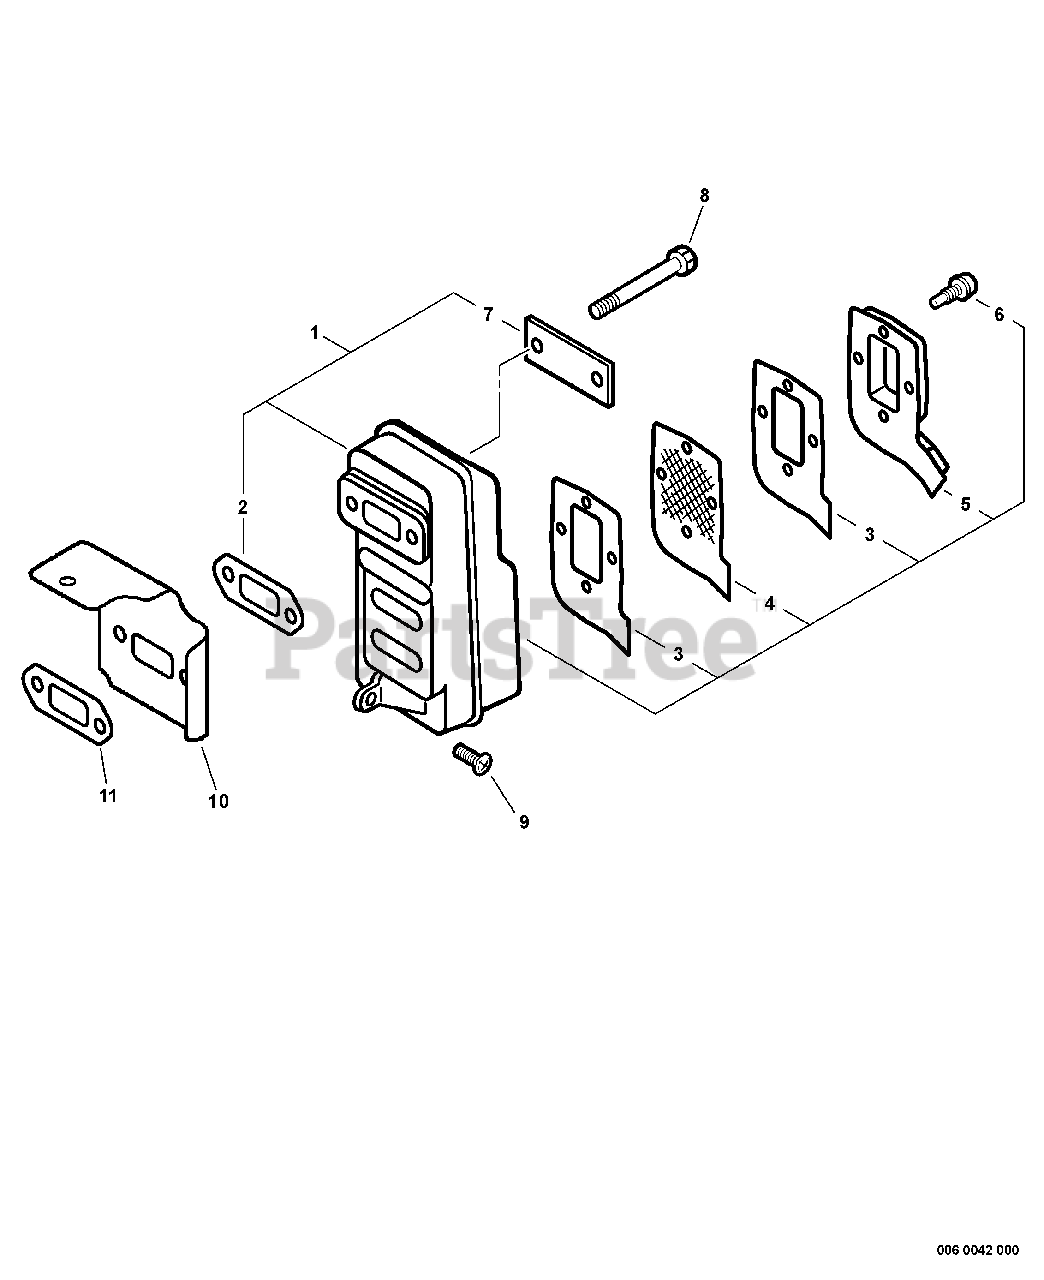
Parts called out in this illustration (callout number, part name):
1	MUFFLER ASSY
2	GASKET, EXHAUST
3	GASKET, EXHAUST
4	SCREEN, SPARK ARRESTER
5	GUIDE, EXHAUST
6	SCREW
7	PLATE
8	BOLT
9	BOLT 5×20
10	COVER, CYLINDER
11	GASKET, EXHAUST
